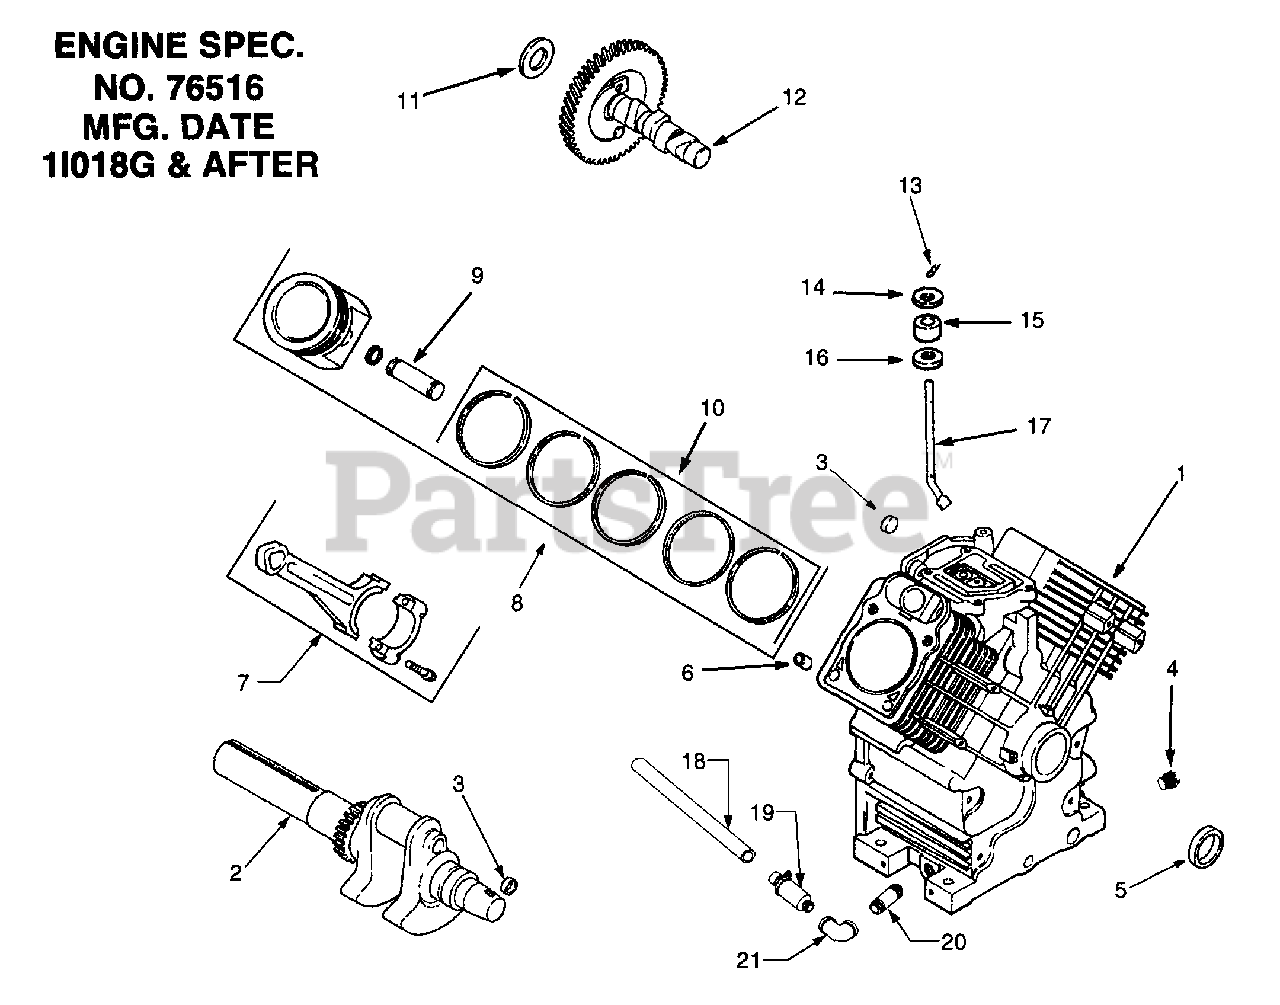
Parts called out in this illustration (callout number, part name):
1	Engine, Complete
2	Crankshaft
3	Plug, Cup
4	Plug, Hex Head, 3/8 NPTF
5	Seal, Oil
6	Pin, Dowel Locating
7	Rod, Connecting, Std
8	Piston w/Ring Set, Std
9	Retainer, Piston Pin
10	Ring Set, Std
11	Shim, Camshaft, .0320
12	Camshaft
14	Washer, Plain
15	Seal, Governor Cross Shaft
16	Washer, Plain
17	Shaft, Governor Cross
18	Hose, Oil Drain 12 in.
19	Drain, Oil
20	Pipe, Straight
21	Elbow, 90°.
